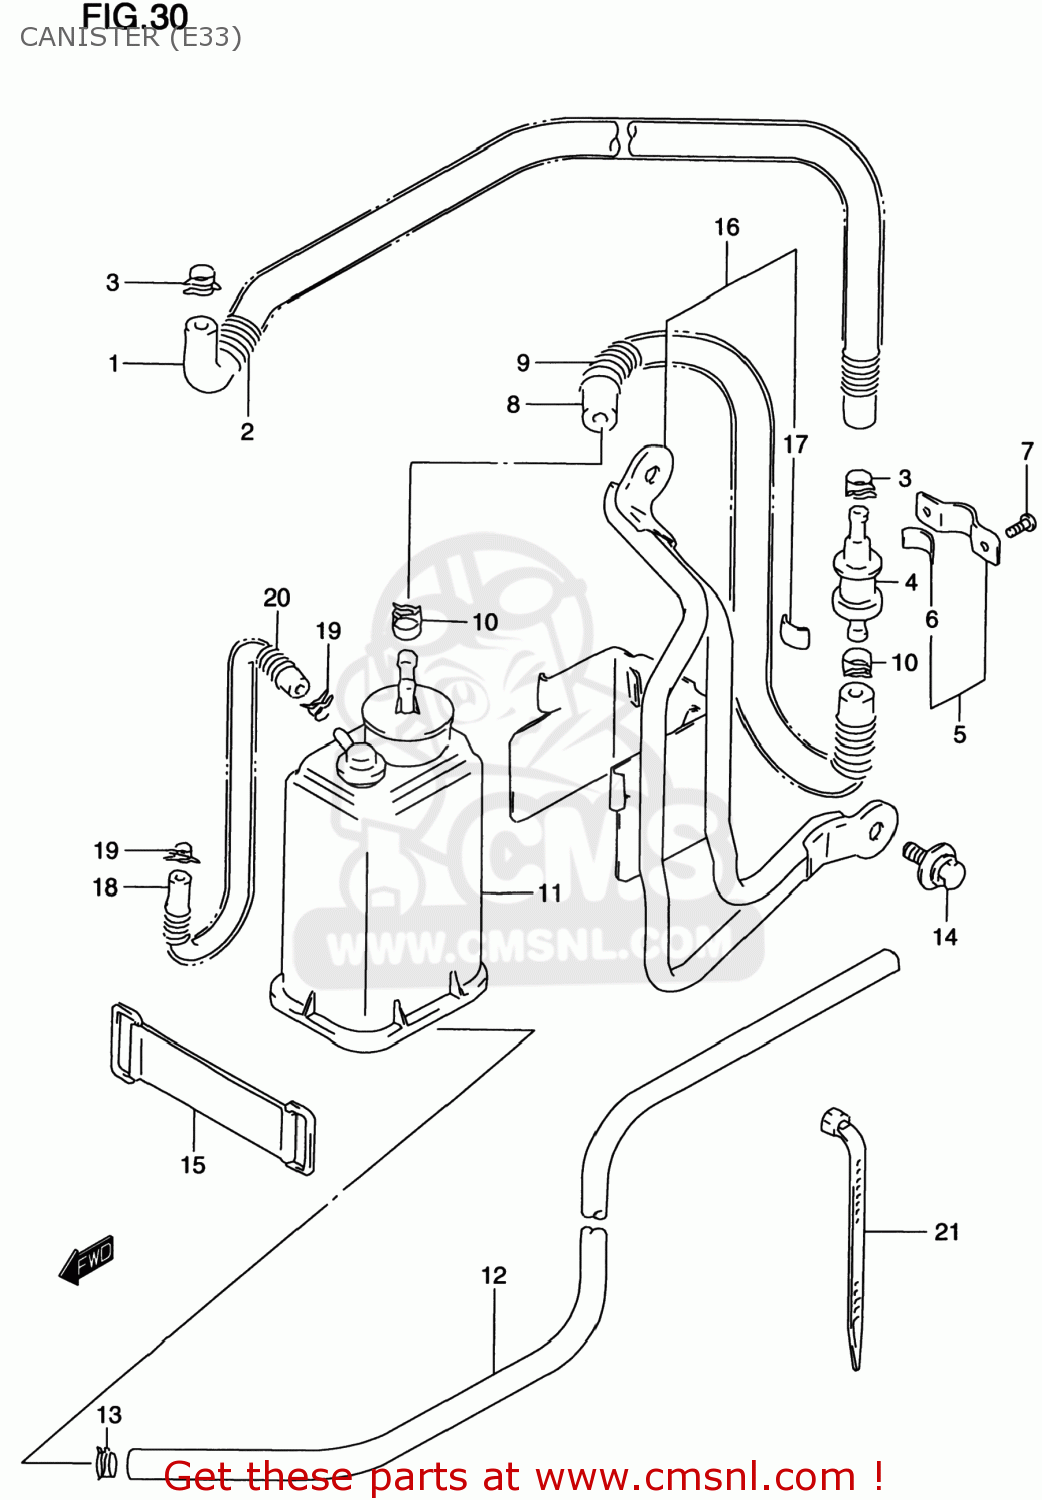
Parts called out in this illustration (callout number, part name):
1	HOSE (5.4X11.4X790)
2	SPRING
3	CLIP
4	VALVE,FUEL TANK BREATHER
5	PLATE,FUEL TANK BREATHER NO.2
6	CUSHION
7	SCREW
8	HOSE
9	SPRING
10	CLIP
11	CANISTER ASSY,CHARCOAL
12	HOSE(7X11X2000)
13	CLIP
14	BOLT(6X16)
15	BAND
16	PLATE,CANISTER
17	CUSHION
18	HOSE
19	CLIP
20	SPRING
21	CLAMP(L:125)
